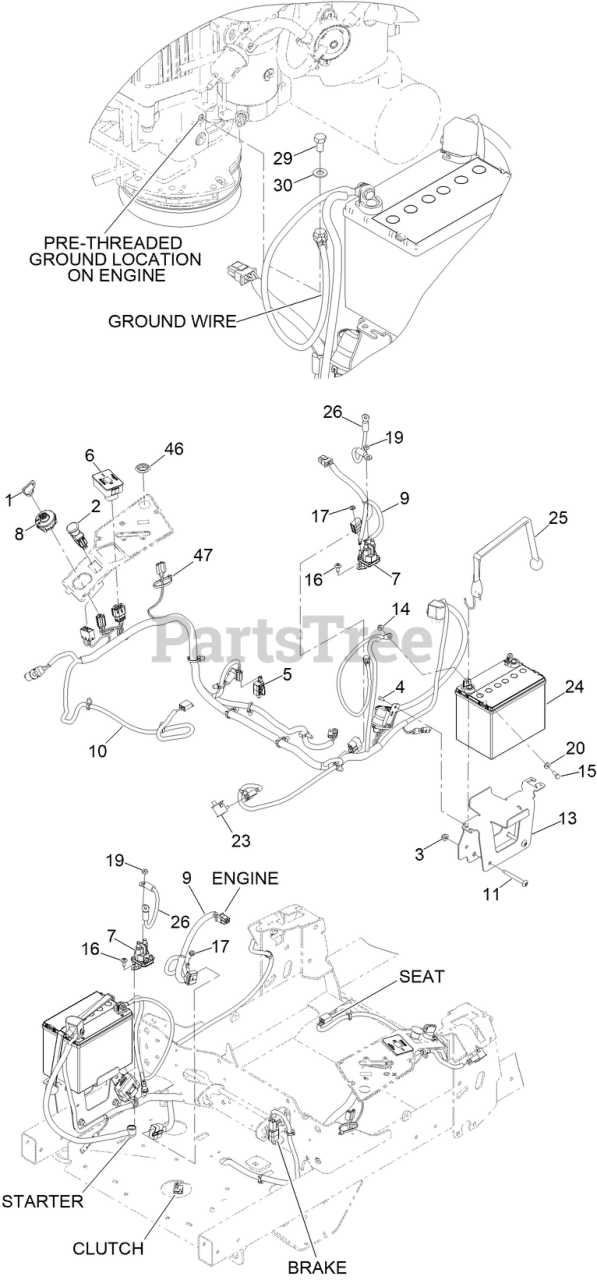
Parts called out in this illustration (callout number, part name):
1	KEY-IGNITION
2	SWITCH-PTO
3	NUT-HF, NI
4	SCREW-FORMING, THREAD
5	SWITCH
6	MODULE ASM
7	SOLENOID
8	SWITCH-IGNITION
9	ADAPTER-HARNESS, WIRE
10	HARNESS-WIRE
11	SCREW-TORX
13	TRAY-BATTERY
14	NUT-HF
15	SCREW-HH
16	SCREW-TORX
17	NUT-KEPS
19	NUT-JAM
20	WASHER-FLAT
23	SWITCH-BAIL
24	BATTERY
25	STRAP-BUNGEE
26	CABLE-BATTERY, POSITIVE
29	SCREW-HH
30	WASHER-PLAIN
46	PLUG-PLASTIC
47	TIE-CABLE
